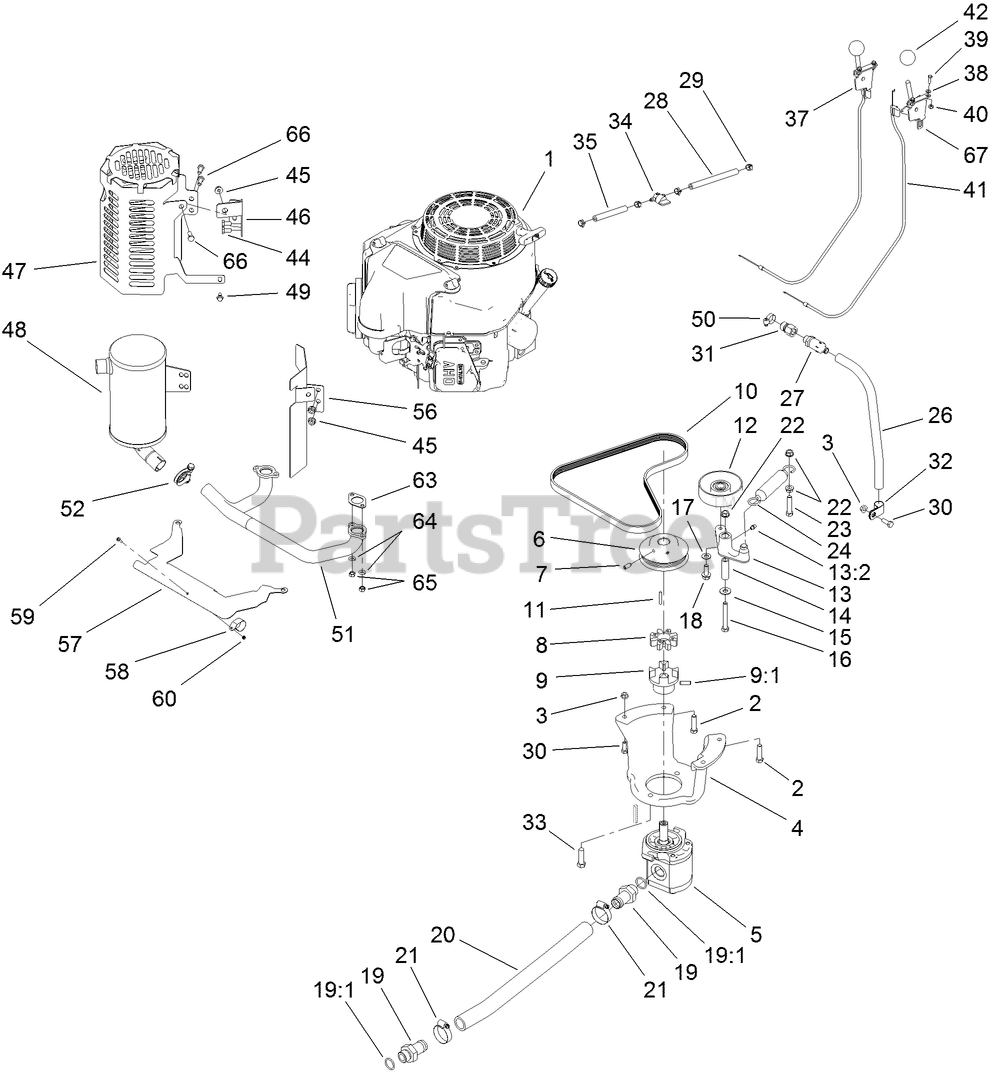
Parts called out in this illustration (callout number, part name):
1	ENGINE-KAWASAKI, FS600V
2	SCREW-HH
3	NUT-HF
4	MOUNT-PUMP
5	GEAR PUMP ASM
6	PULLEY-ENGINE
7	SCREW-SET, HSH
8	COUPLER-SPIDER
9	COUPLER-FLEX
9:1	SCREW-SET
10	BELT-V
11	KEY-SQUARE
12	PULLEY-IDLER
13	IDLER ARM ASM
13:2	FITTING-GREASE
14	BUSHING-IDLER
15	WASHER-FLAT
16	SCREW-HH
17	WASHER-FLAT
18	SCREW-HHF
19	FITTING
19:1	O-RING
20	HOSE-SUCTION
22	NUT-HHF, WHIZ
23	SCREW-HH
24	Spring-Extension
26	HOSE-VENT
27	VALVE-DRAIN, OIL
28	HOSE-FUEL
29	CLAMP-HOSE
30	SCREW-HH
31	Adapter
32	CLAMP-R
33	SCREW-HH
34	VALVE-FUEL
35	HOSE-FUEL
37	LEVER-CONTROL
38	WASHER-FLAT
40	NUT-LOCK, NI
41	CABLE-CONTROL
44	SCREW-HH
45	NUT-HF
46	BRACKET-GUARD, MUFFLER
47	SHIELD-MUFFLER
48	MUFFLER
49	SCREW-HHF
50	CLAMP-HOSE
51	MANIFOLD
52	CLAMP-MUFFLER
56	BRACKET-SHIELD, HEAT
57	PLATE-SHIELD, HEAT
59	SCREW-PAN
60	NUT-HEX
63	GASKET-EXHAUST
64	WASHER-SPRING
65	NUT-HEX
66	SCREW-HH
67	LEVER-CONTROL
